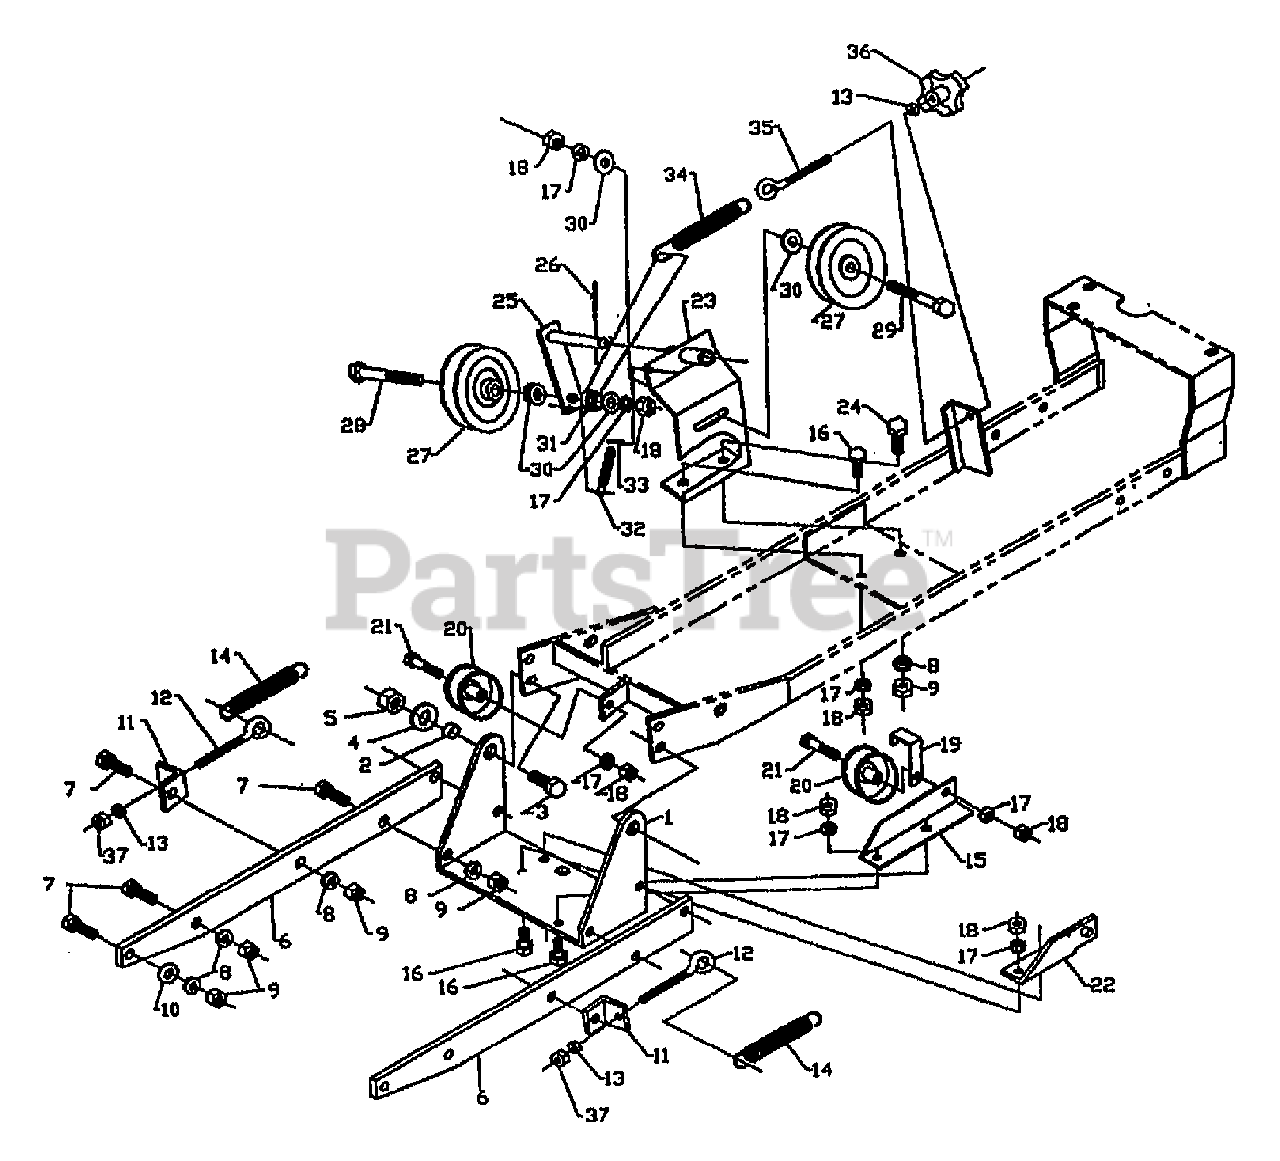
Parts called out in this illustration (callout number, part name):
1	BRACKET-PIVOT
2	SPACER-TUBULAR
3	SCR-HH 1/4-20X1.25 G5 ZP
4	WASHER-1.06X.531X.1 ZP
5	NUT-TOP LOCK 1/2-13 ZP
6	BAR-FLAT ATTACHING
8	WASHER-LK .438 ZP
9	NUT-HH 7/16-14X.375
10	WASHER-1.06X.531X.1 ZP
11	BRACKET-SPRING
13	WASHER-FLAT 5/16 SAE
14	SPRING-1.13 DIA X 5.75
15	SUPT-IDLER
16	SCR-HH 3/8-16X1.0 G5 ZP
17	WASHER-LK .375 @ DEPL
18	NUT-HEX 3/8-16 ZP
19	GUIDE-BELT
20	PULLEY-IDLER
21	SCR-HH 3/8-16X1.75 G5 ZP
22	BRACKET-PUSH
23	BRACKET-PULLEY
24	SCR-HH 1/2-14X1.00
25	IDLER-BELT
26	PIN-COTTER .120X1.00 ZP
28	SCR-HH 3/8-16X2.50
29	SCR-HH 3/8-16X1.75 G5 ZP
30	WASHER-.94X.468X.065
31	SPRING FIXATION
32	SPRING-.5 DIA X 4.5
33	PIN-COTTER .125 X .75 ZP
34	SPRING-1.13 DIA X 6.25
35	BOLT-EYE .31 NC X 5.0
37	NUT-HEX 5/16-18 ZP
